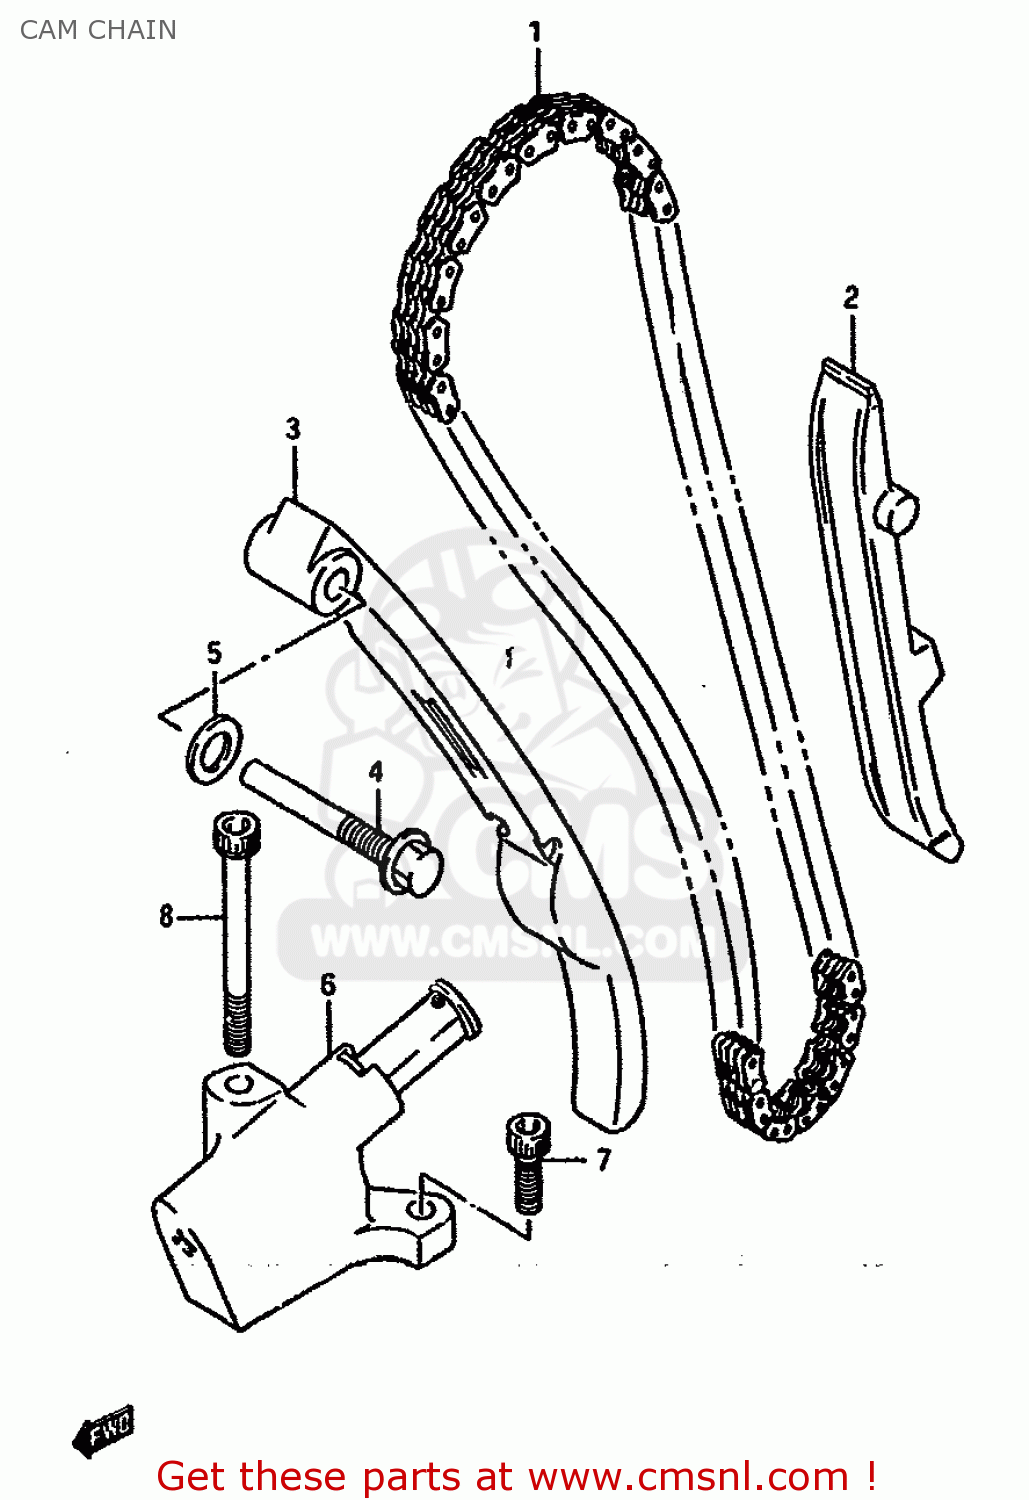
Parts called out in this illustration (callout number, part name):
1	CHAIN,CAMSHAFT DRIVE
2	GUIDE,CAM CHAIN
3	TENSIONER,CAM CHAIN
4	BOLT,CAM CHAIN TENSIONER
5	GASKET 8.2X14X1 (NAS)
6	ADJUSTER ASSY,TENSIONER
7	BOLT
8	BOLT
